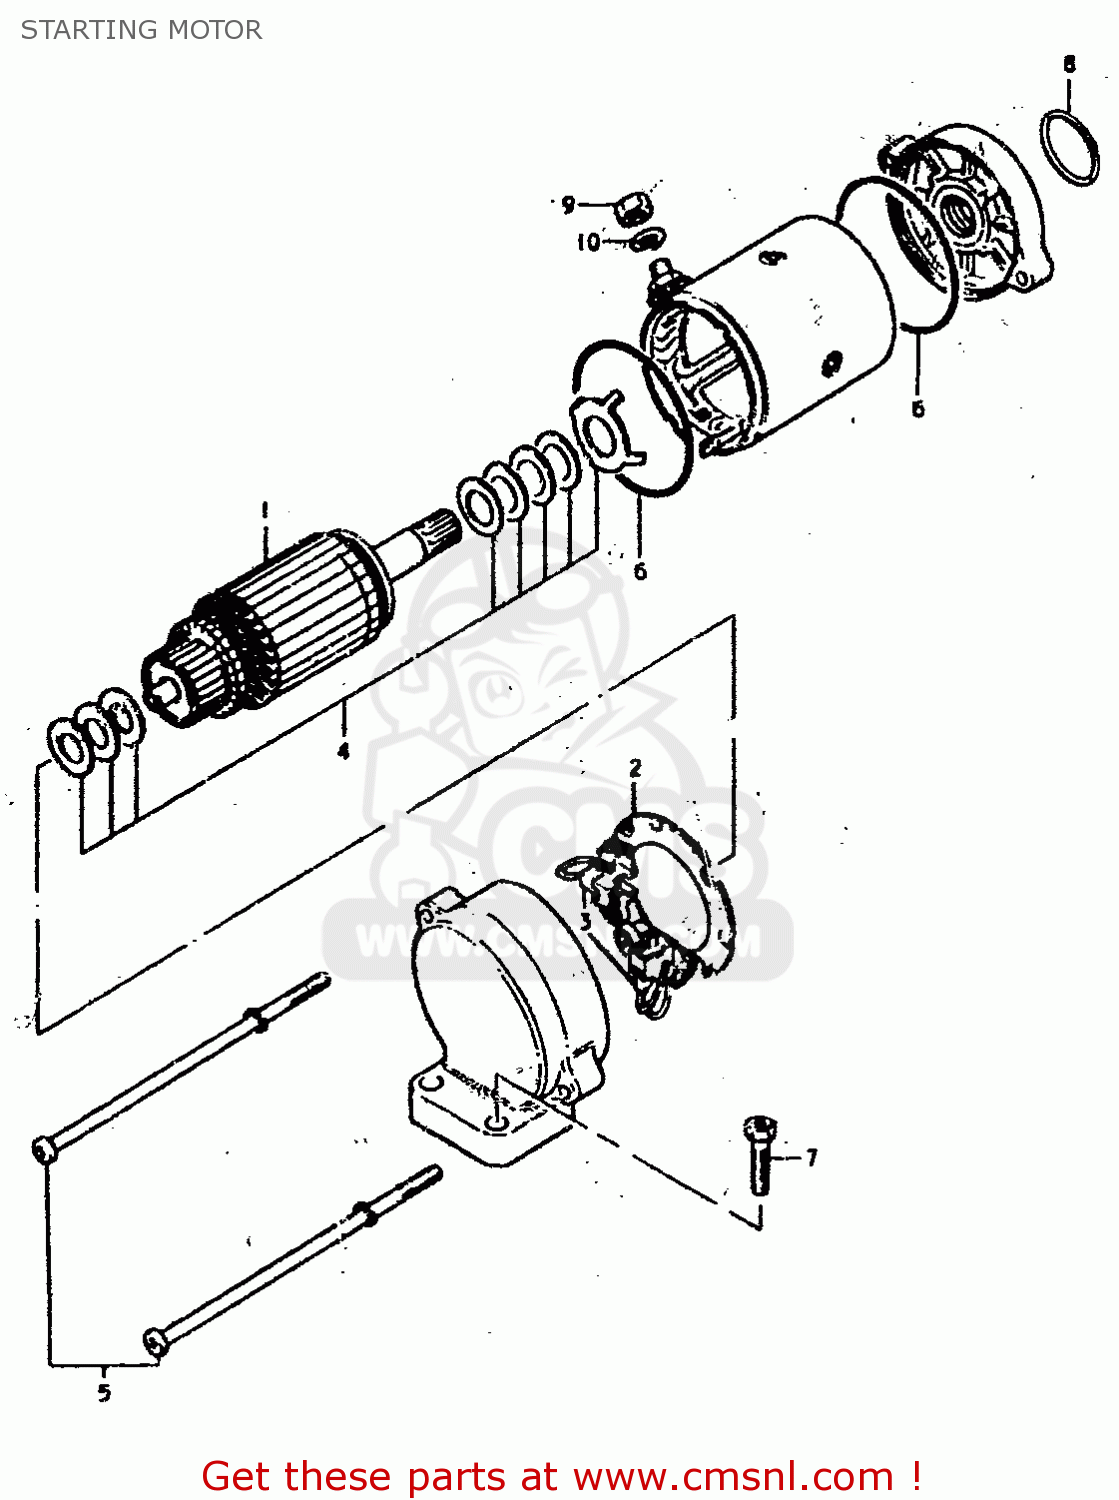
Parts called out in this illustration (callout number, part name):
1	ARMATURE
2	HOLDER ASSY
3	BRUSH SET
4	SHIM SET
5	BOLT,STARTING MOTOR HOUSING
6	O RING
7	SCREW
8	O RING(D:2,ID:24.5)
9	NUT 6MM
10	LOCK WASHER
